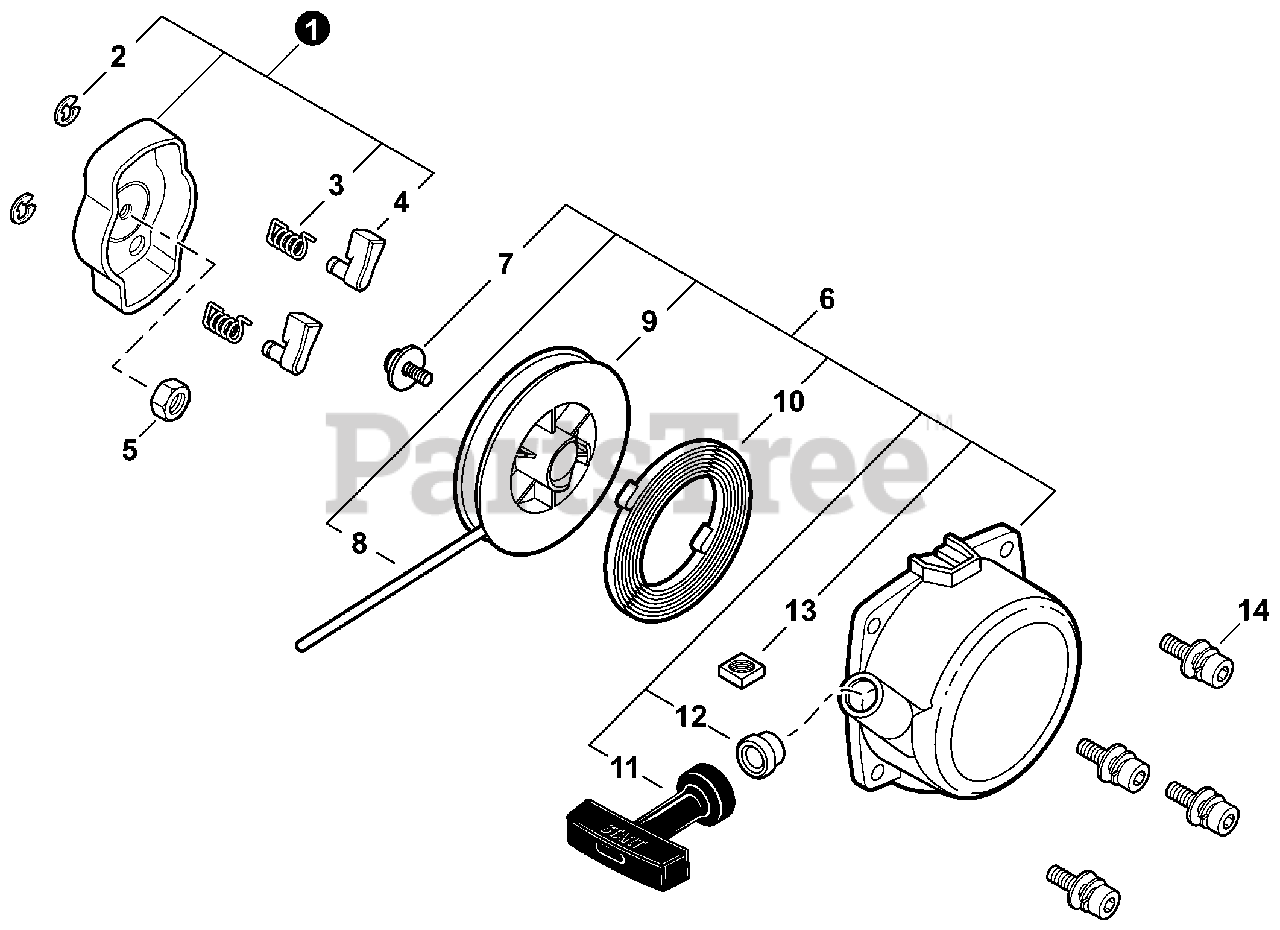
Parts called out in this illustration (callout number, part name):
1	PAWL ASSY, STARTER
2	E-RING 4
3	SPRING, RETURN
4	PAWL, STARTER
5	NUT 8×1.25
6	STARTER ASSY, RECOIL
7	SCREW
8	ROPE, STARTER 3.5×850
9	REEL, ROPE
10	SPRING, RECOIL
11	GRIP, STARTER
12	GUIDE, ROPE
13	NUT M5
14	BOLT 4×12
